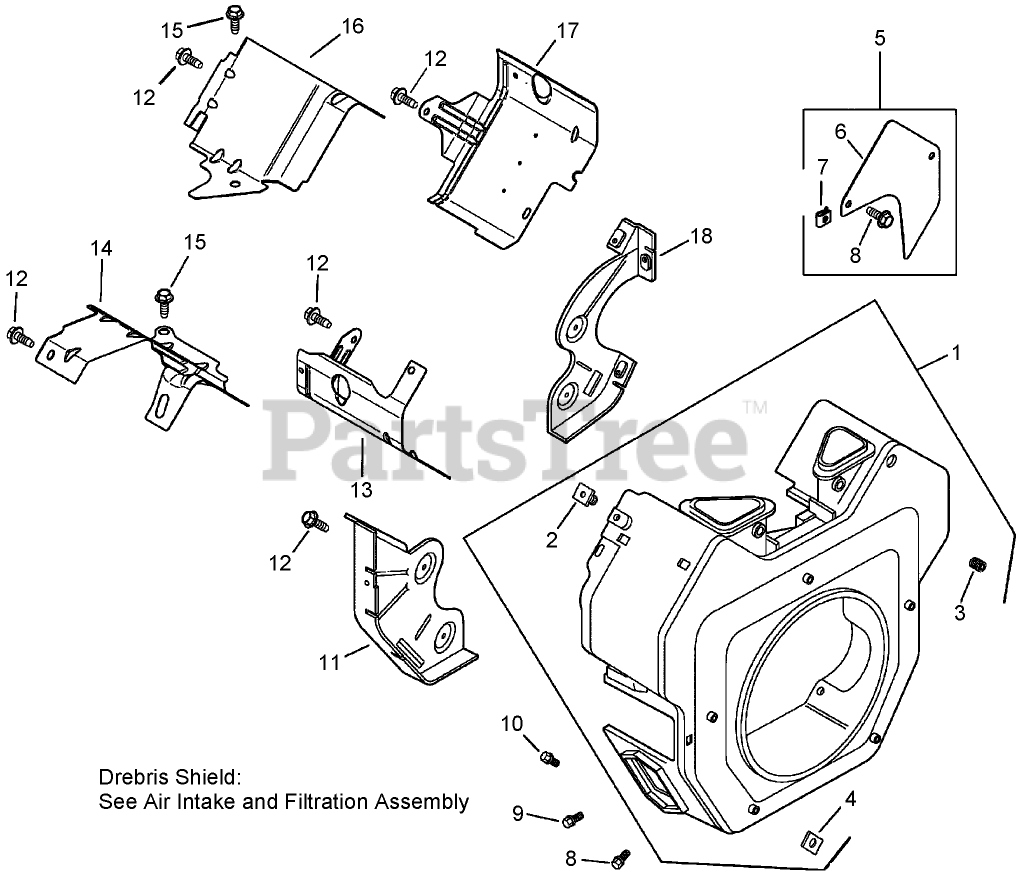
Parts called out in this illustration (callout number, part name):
1	Housing-Blower (Includes 2-4, 6)
2	NUT-PLASTIC
3	Screw-Set (10-24X.25)
4	Nut-Plastic
5	Access Cover Kit (Includes 6, 7, 8 (qty.4))
6	Panel-Access
7	Clip-Mounting
8	SCREW-FLANGE, THREAD FORMING (M6X1.0X16)
9	Screw-Hex Flange, Heavy (M5x0.8x16)
10	SCREW-FLANGE, THREAD FORMING (M5X0.8X16)
11	Plate-Backing (No. 2 Side)
12	SCREW-FLANGE, THREAD FORMING (M5X.8X20)
13	Baffle-Barrel, Cylinder (No. 2 Side)
14	BAFFLE-VALLEY (No. 2 SIDE)
15	SCREW-HHFTF (M5X.80X10)
16	BAFFLE-VALLEY (No. 1 SIDE)
17	Baffle-Barrel, Cylinder (No. 1 Side)
18	Plate-Backing (No. 1 Side)
